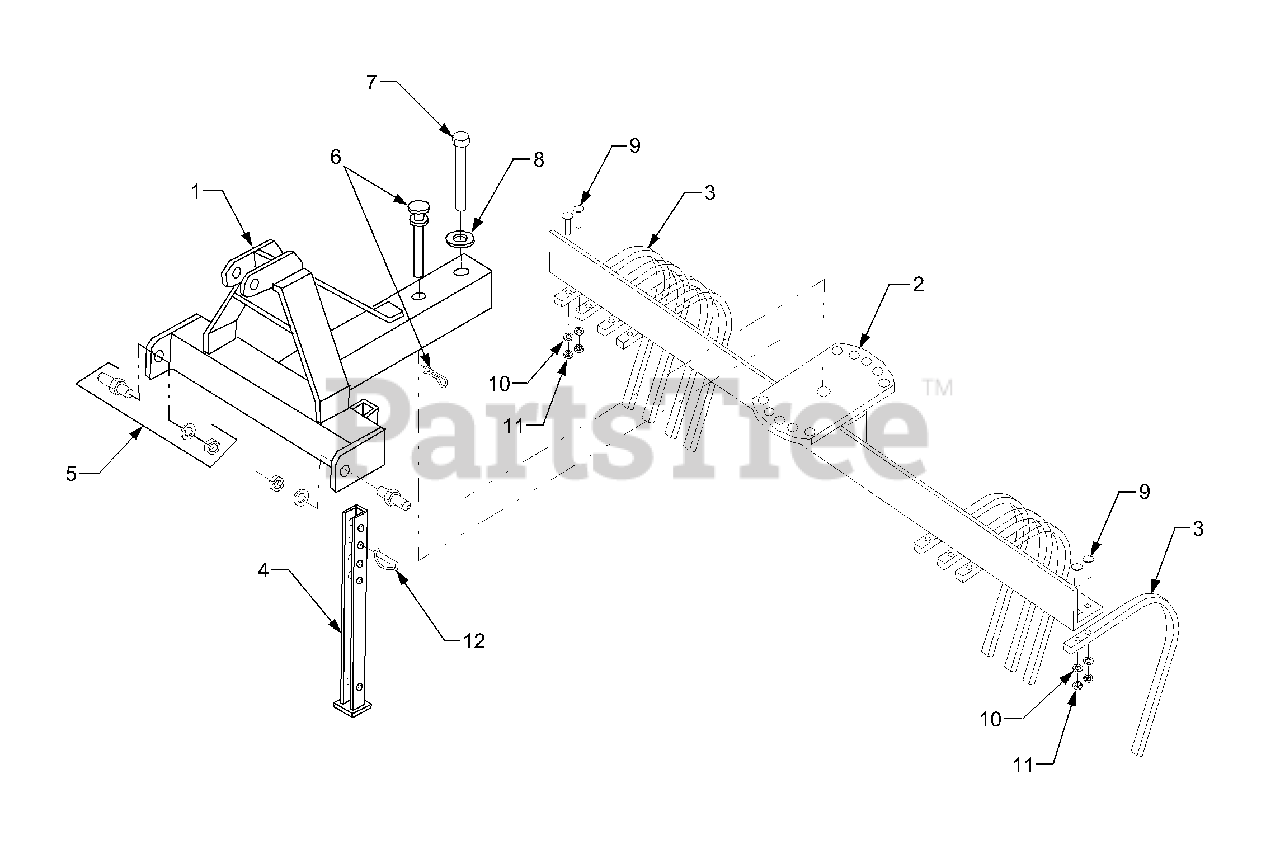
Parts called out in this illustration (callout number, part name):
5	Hitch Pin w/Lockwasher and Nut, 7/8
6	Swivel Pin w/Cotter Pin
7	Hex Bolt, 1.0 x 6.0
8	Flat Washer, 1.0 ID
9	Carriage Bolt, 3/8-16 x 1.25
10	Lockwasher, 3/8
11	Hex Nut, 3/8
